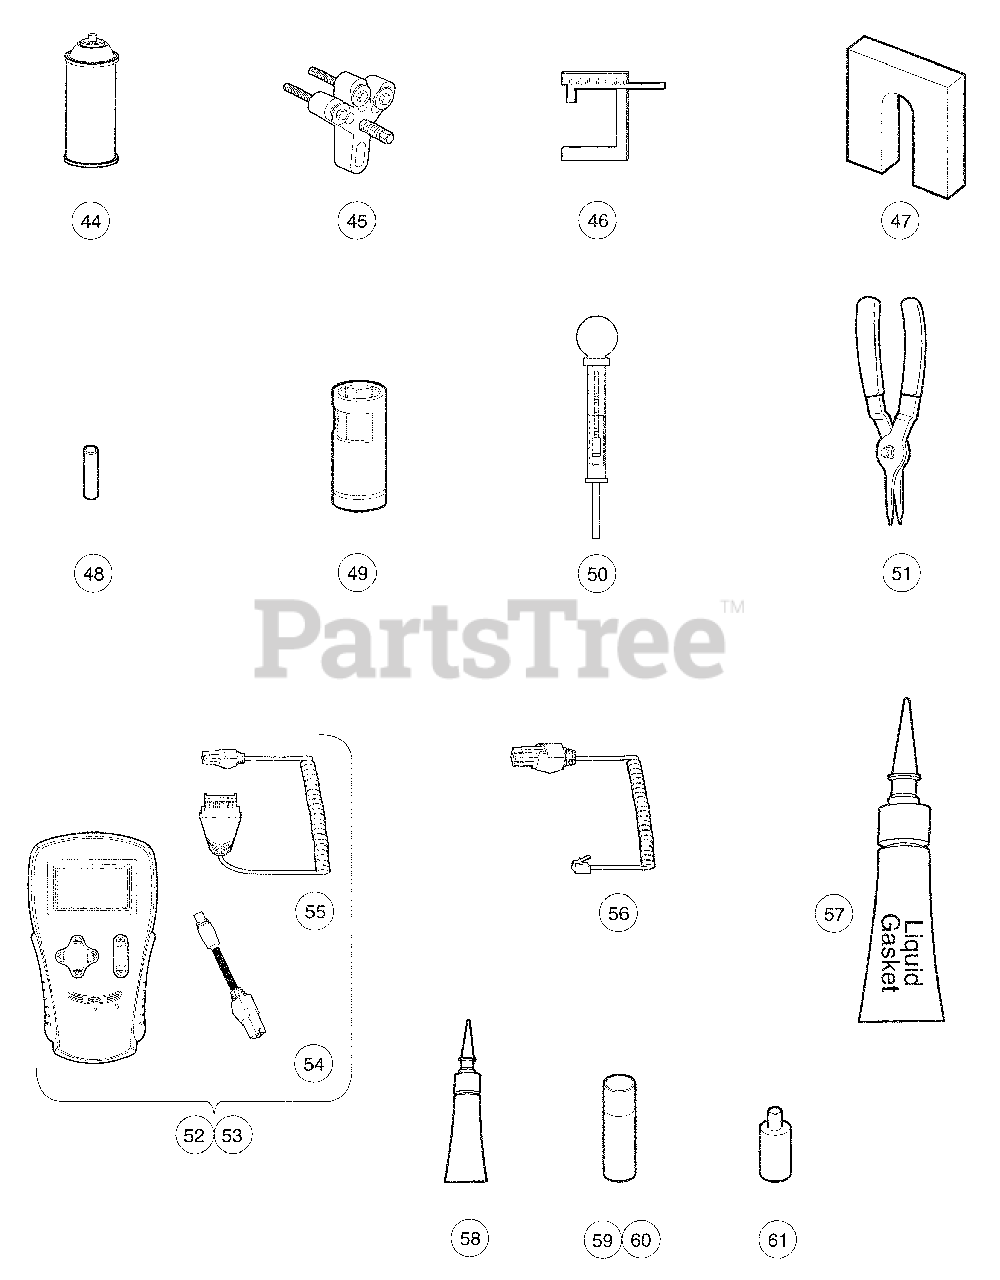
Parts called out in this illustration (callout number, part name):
1	Accelerator Pedal Adjustment Tool
2	Adhesive, Guide Ring, 3-Gram Tube
4	Battery Discharge Machine, 36/48 Volt
5	Battery Terminal Protector Spray
6	Battery Thermometer
7	Bearing and Oil Seal Remover Assembly
8	Bearing Driver Set
9	Bearing Puller
10	Bearing Puller Wedge Attachment
11	Brake Adjustment Tool
12	Brake Cable Release Tool
13	Brake Pedal Adjustment Tool Kit
14	Brake Pedal Adjustment Tool
15	Brake Pedal Tension Tool
16	Calibration Test Module
17	Cam Installation Tool
18	Charger Bezel Tool
19	Clutch Removal Tool (for 4x4 vehicles)
20	Clutch Tool Kit
21	Clutch Alignment Tool
22	Drive Clutch Puller
23	Drive Clutch Hub Puller
24	Driven Clutch Cam Puller
25	Driven Clutch Puller Plug
26	Drive Clutch Holder Tool Assembly
27	Press Weldment
28	Drive ClutchFixed Sheave Tool (for 4x4 vehicles)
29	Driven Clutch Spring Compression Base (for 4x4 vehicles)
30	Driven Clutch Spring Compression Collar (for 4x4 vehicles)
31	Driven Clutch Spring Compression Nut (for 4x4 vehicles)
32	Drive Clutch Spider Removal Tool (for 4x4 vehicles)
33	Communication Display Module
34	Compression Gauge and Adapter
35	Continuity Tester
36	Cutter, Valve Seat, #122
37	Cutter, Valve Seat #115
38	Wrench, T, #505
39	Adapter, T-Wrench
40	Cutter, Valve Seat, 60 Degree (requires item 51)
41	Pilot, 6.6 MM
42	Pilot, 6.62 MM
43	Pilot, 6.65 MM
44	Dry Moly Lubricant
45	Flywheel Puller Kit
46	Gauge, Carburetor Float Level
48	Governor Shaft Installation Tool
49	Hydraulic Brake Adjuster (for HUV 4213)
50	Hydrometer
51	Internal Retaining Ring Pliers
52	IQ Display Module (IQDM) Kit
53	IQ Display Module (IQDM-P) Kit
54	Adaptor, Cable
55	IQDM Series 2 Cable
56	IQDM Series 1 Cable
57	Liquid Gasket
58	Moly-Teflon Lubricant (4-oz. (113-gram) tube)
59	Paint, Touch-Up – Beige
59	Paint, Touch-Up – Black
59	Paint, Touch-Up – Burgundy
59	Paint, Touch-Up – Classic Blue
59	Paint, Touch-Up – Dark Gray
59	Paint, Touch-Up – Dark Green
59	Paint, Touch-Up – Gray
59	Paint, Touch-Up – Red
59	Paint, Touch-Up – Royal Blue
59	Paint, Touch-Up – White
60	Paint, Precedent Underbody – Gray
61	Paint Pen, Touch-Up, Precedent Underbody – Black
62	Piston Ring Compressor Kit (FE290, FE350 and FE400 engines)
63	Piston Ring Pliers
64	Puller, Special Use (for Kubota D722 Diesel Engines)
65	Retaining Ring Pliers, 45° External
66	Retaining Ring Pliers, 90° Internal
67	Safety First Card (50 per pack)
68	Seal Puller
69	Spanner Wrench
70	Steering Column Bearing Press Tool
71	Steering Column Retaining Ring Tool
72	Steering Wheel Puller Tool
73	Tachometer
74	Tachometer Diesel Probe
75	Transaxle Axle Seal Tool
76	Transaxle Pinion Seal Tool
77	Transmission Tool Kit
82	Valve Clearance Adjuster Screw Holder (for FE290 engines only)
83	Valve Guide Driver
84	Valve Guide Reamer (FE290, FE350, and FE400 only)
85	Valve Guide Reamer, 6.6 mm
86	Valve Seat Cutter Guide
87	Valve Seat Cutter T-Wrench
88	Valve Seat Cutter, 45°
89	Valve Seat Cutter, 45°/30°
90	Valve Spring Compressor
91	Volt Ohm Meter
92	Tool, Tensioning, Starter Generator
